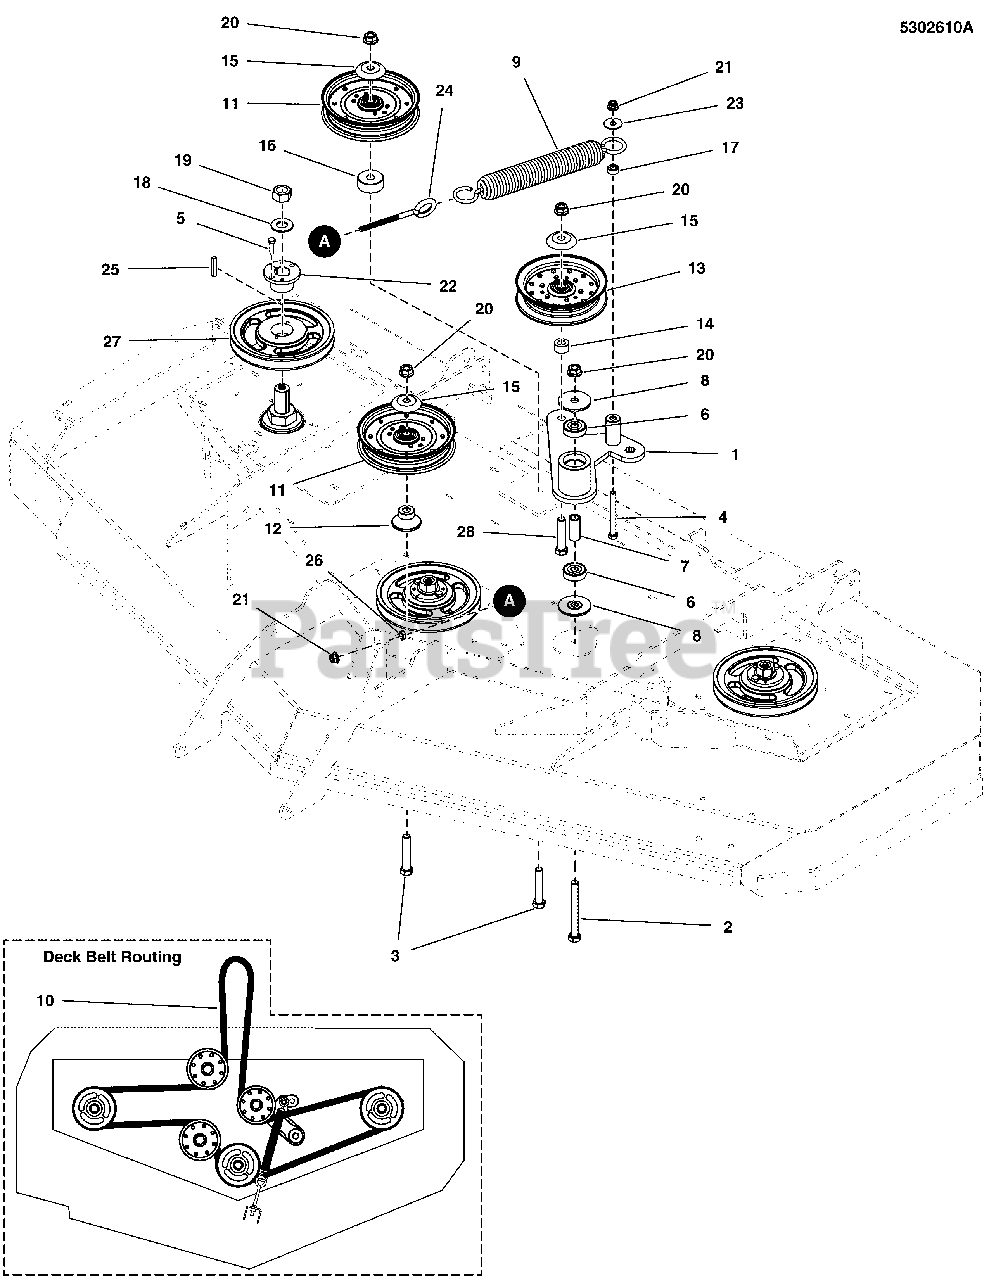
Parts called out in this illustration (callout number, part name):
1	WELD, IDLER ARM, CUTTER DECKS - BLK
2	BOLT, 1/2-13 X 4-1/2 GD5 CZ
3	BOLT, 1/2-13 X 2-3/4 GD5 CZ
4	BOLT, 3/8-16 X 3-1/2 GD5 CZ
5	BOLT, 1/4-20 X 2-1/4 GD5 CZ
6	BEARING, 6203-1/2", SEALED
7	SPACER, .510 X .750 X 1.749, CZ
8	SPACER, IDLER ARM, 1/2 X 2.25
9	SPRING, EXT, 1.5ODX12.25X.234WIRE BLK
10	BELT, 5V, 193.90"EL, LRG ARAMID, WRP, RC
11	PULLEY, FLAT IDLER, 6-3/4"
12	IDLER MOUNT
14	SPACER, .52 X 1.00 X .56, PM, CZ
15	SHIELD, PULLEY BEARING, CZ
16	SPACER, .51 X 1.75 X .75
17	SPACER, .39 X .75 X .38, PM, CZ
18	WASHER, 3/4 BELLEVILLE
19	NUT, 3/4-16 HEX
20	NUT, 1/2-13 HEX NYLOCK FLANGE
21	NUT, 3/8-16 HEX NYLOCK FLANGE
22	BUSHING, TAPERED HUB
23	WASHER-3/8 FENDER
24	EYE BOLT, 3/8-16 X 6, 3THRD, 1EYE, CZ
25	KEY 1/4 SQ X 1 1/2 LONG
26	NUT, 3/8-16 HEX JAM
27	PULLEY, SPINDLE, BH72
28	BOLT, 1/2-13 X 2-1/2 GD5 CZ
